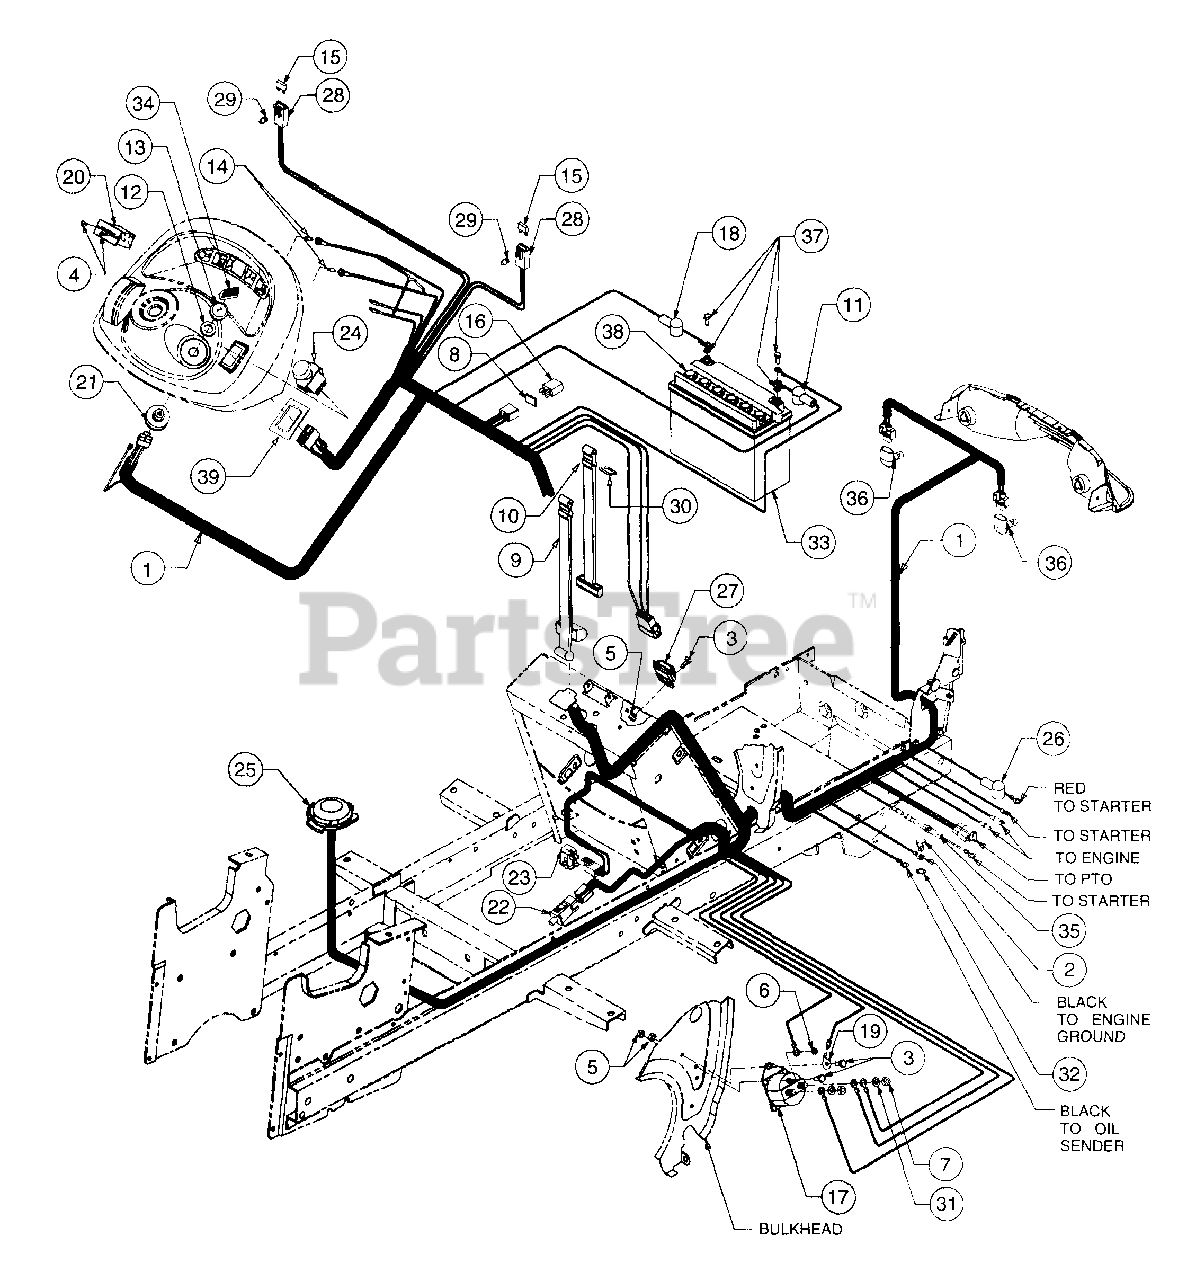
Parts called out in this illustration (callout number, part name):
1	Wire Harness, Main
2	Screw, Hex Cap, 3/8-16 x .50
3	Screw, Hex Cap, 1/4-20 x .625 GR5
4	Screw, Truss Hd Tapp, #6 x .62
5	Nut, Hex Sems, 1/4-20
6	Nut, Hex, #10-32
7	Nut, Hex, 5/16-18 GR5
8	Gasket, Silicone
9	Strap, Battery Retainer
10	Strap, Battery Retainer
11	Cover, Terminal Black
12	Nut, Ignition Switch
13	Cap, Ignition Switch
14	Bulb, Indicator
15	Fuse, 20 Amp
16	Relay
17	Solenoid, Starter
18	Cover, Terminal Red
19	Lug, Quick Connect
20	Hour Meter
21	Switch, Ignition
22	Switch, Interlock (Brake)
23	Switch, Snap Mount - Normally Closed
24	Switch, PTO
25	Switch, Seat
26	Cover, Terminal Red
27	Module, Voltage Sensor
28	Holder, Fuse
29	Clip, Fuse Holder Mounting
30	Hook, Wire Rectangular
31	Washer, Lock, 5/16
32	Washer, External Lock, 3/8
33	Battery
34	Key,Ignition (Set of 2)
35	Diode Assembly w/Lead
36	Bulb, Head Lamp
37	Battery Cable Hardware (Set of 2)
38	Cap, Battery
39	Bracket, PTO Switch Retainer
